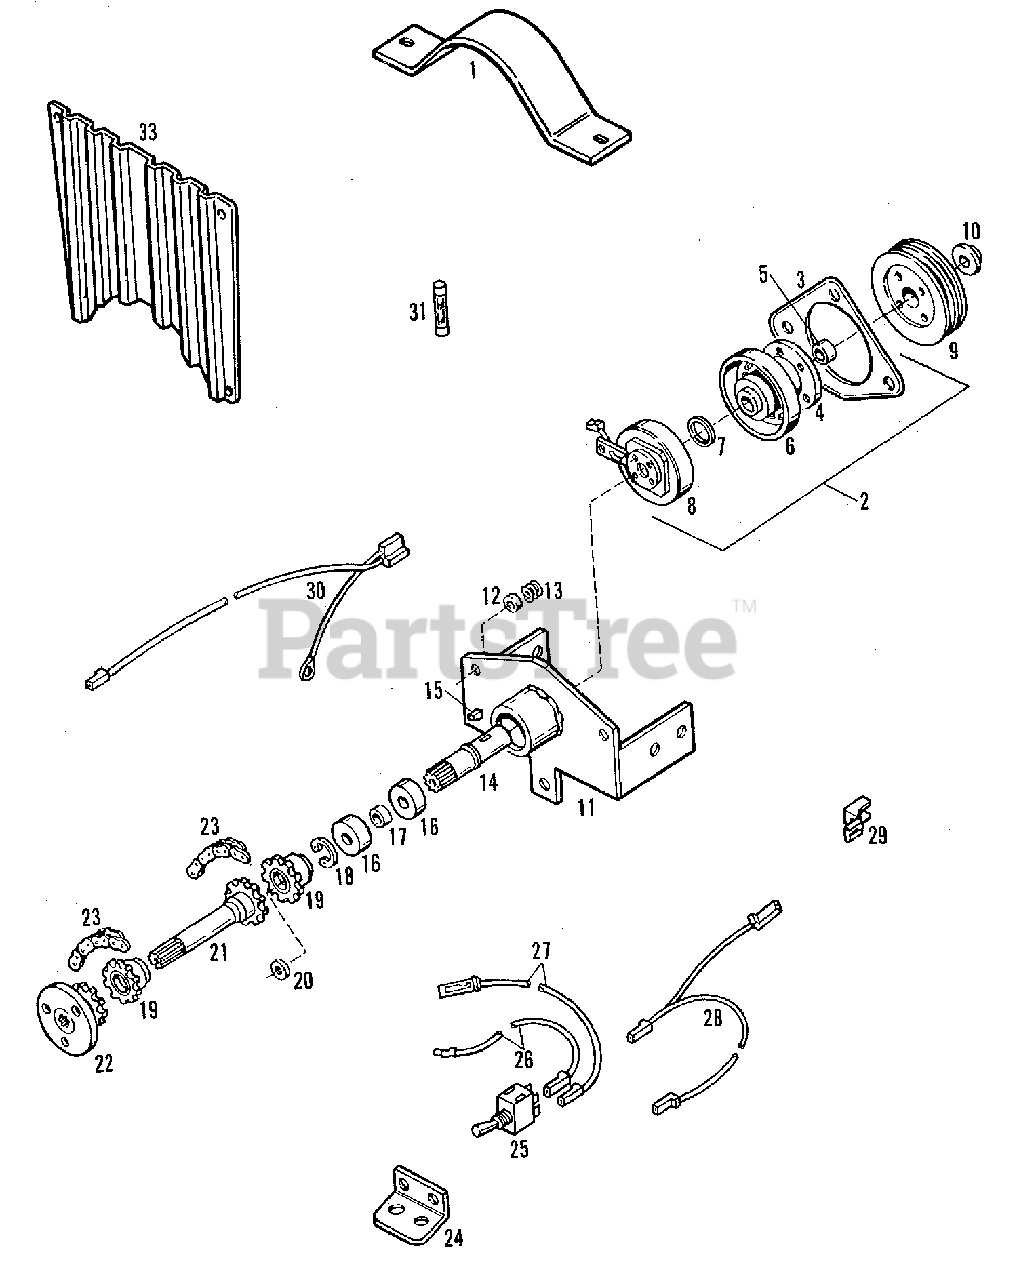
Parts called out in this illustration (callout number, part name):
1	GUARD, Belt
1	CAPSCREW, 5/16NC x 3/4
1	WASHER, Plain, 11/32 x 3/4 x 16 Ga.
1	LOCKWASHER, 5/16
1	NUT, 5/16NC
2	BRAKE & CLUTCH ASSEMBLY
3	DRUM, Brake
4	FLANGE ASSEMBLY, Brake Shoe
6	ROTOR & ARMATURE ASSEMBLY
7	SPACER, Rotor
8	FIELD ASSEMBLY
8	CAPSCREW, Hex Socket Head, No 10NF x 1/2, Gr.8
8	LOCKWASHER, Internal Tooth, No. 10
9	PULLEY, Electric Clutch
9	SCREW, Taptite, 5/16NC x 3/4
10	CAPSCREW, Large Flange, Whizlock, 3/8NC x 1-1/4
11	SUPPORT ASSEMBLY, Clutch
11	CAPSCREW, 3/8NF x 2-1/2
11	LOCKWASHER, 3/8
11	NUT, Lock, 3/8NF
11	CAPSCREW, 7/16NC x 1-1/2
11	LOCKWSHER, 7/16
11	NUT, 7/16NC
13	SPRING, Compression
18	RING, Retaining
19	SPROCKET ASSEMBLY
19	CAPSCREW, Large Flange, Whizlock, 3/8NC x 3/4
21	SPROCKET ASSEMBLY
22	DRIVE ASSEMBLY, Crankshaft
22	CAPSCREW, M10 x 1-1/4 x 25MM
22	LOCKWASHER, 7/16
23	CHAIN, Bulk, 3/4 Pitch
23	LINK, Connecting
24	BRACKET, Switch
26	WIRE ASSEMBLY, Switch
27	WIRE ASSEMBLY, Switch
28	WIRE ASSEMBLY
29	ADAPTER, 2-Way
30	WIRE ASSEMBLY, Clutch
31	FUSE, 20Amp
32	DECAL, Switch
33	SCREEN, Grille-Cut-Out
